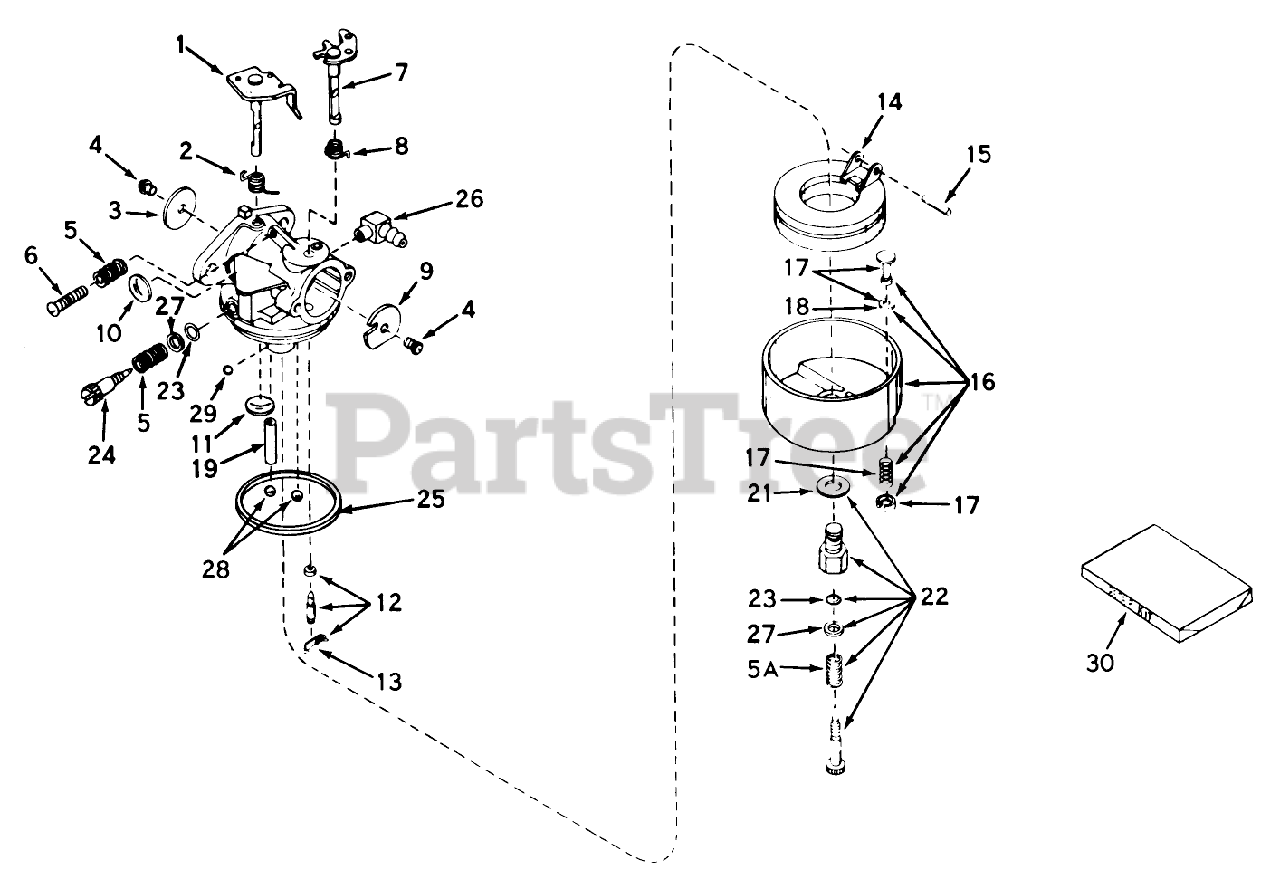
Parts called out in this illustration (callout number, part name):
1	Throttle Shaft and Lever ASM
2	Spring, Throtte Return
3	Shutter-Throttle
4	Screw-Shutter
5	Spring-Tension
5A	Spring
6	Screw-Throttle Crack Screw / Idle Speed
7	Shaft Lever Assy., Choke
8	Spring, Choke return
9	Shutter, Choke
10	Plug-Welch, Idle Mixture Well
11	Plug-Welch, Atmospheric Vent
12	Inlet Needle, Seat Clip Assy. (Incl. No. 13)
13	Clip-Spring
14	Float,Carburetor
15	Shaft-Float
16	Bowl Drain Assy., Float (Incl. No. 17)
17	Bowl Drain ASM
18	Gasket-Plunger, Drain
21	Washer-Bowl Nut
22	Adjustment Screw Assembly, Main (Incl. Nos. 5A, 21, 23 27)
23	ORing
24	Screw, Idle Adj.
25	O Ring-Bowl, Float
26	Fitting Fuel Inlet
27	Washer
28	Plug, Cup
29	BalI, Steel
30	Repair Kit
